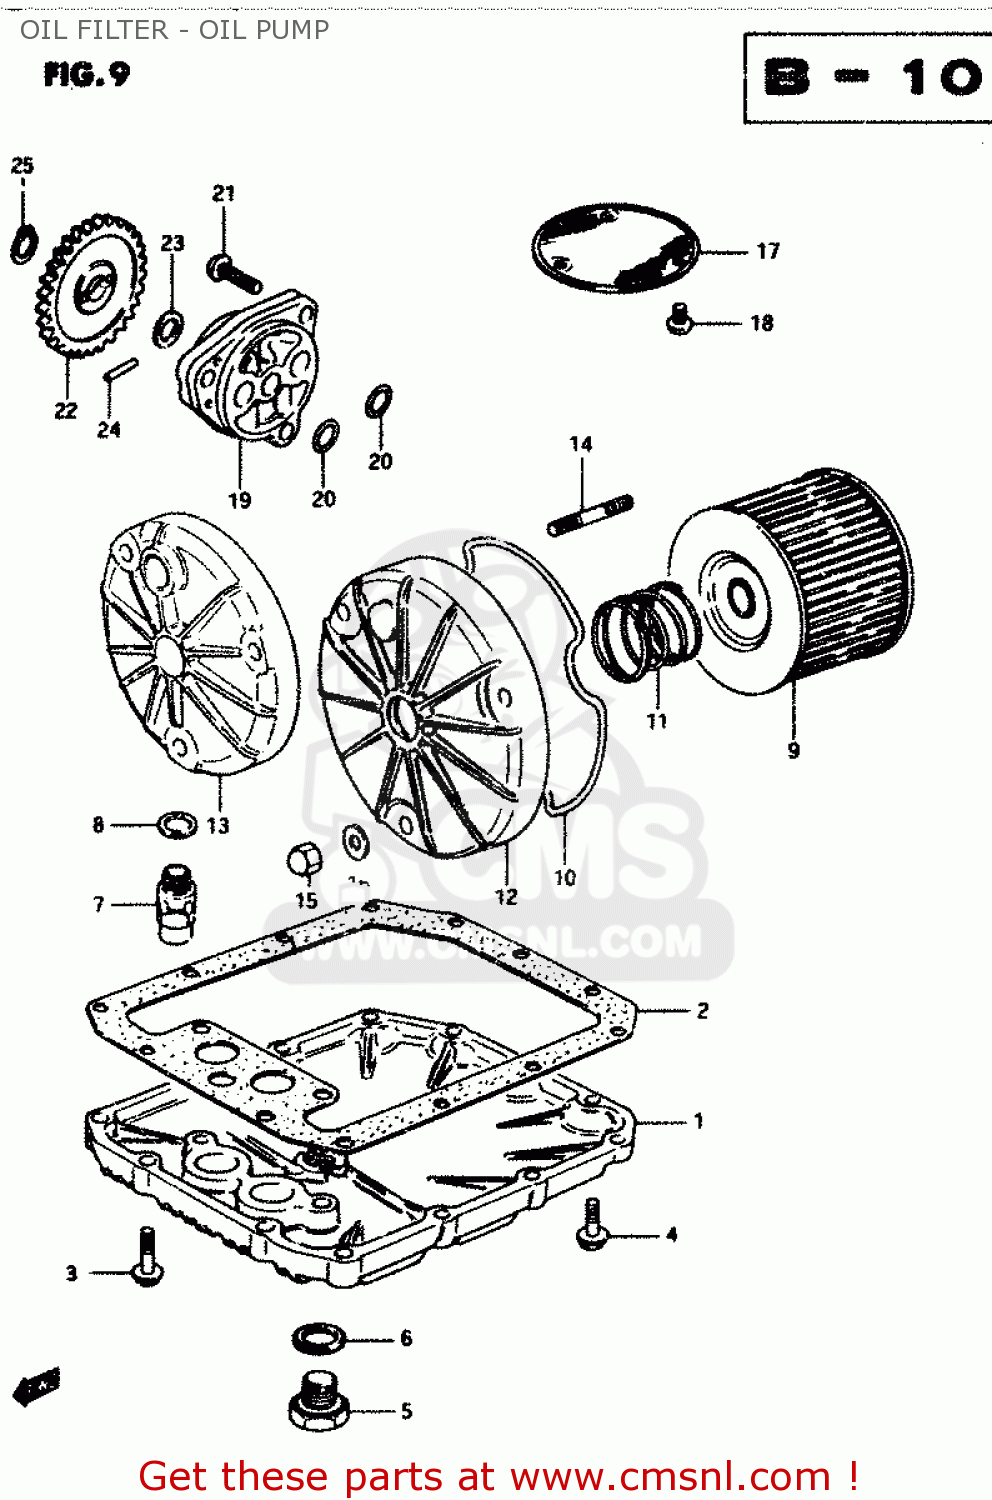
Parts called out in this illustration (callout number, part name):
1	PAN,OIL
2	GASKET,OIL PAN (MCA)
3	BOLT
4	BOLT
5	PLUG
6	GASKET(14X19.2X2) (NAS)
7	REGULATOR ASSEMBLY,ENGINE
8	WASHER
9	FILTER ASSY,ENGINE OIL
10	O RING,OIL FILTER CHAMBER CAP
11	SPRING
12	CAP,ENGINE OIL FILTER
13	CAP,OIL FILTER
14	STUD 6X20
15	NUT
16	WASHER
17	STRAINER,ENGINE OIL
18	SCREW 6X12
19	PUMP ASSY,ENGINE OIL
20	O RING(D:1.9,ID:13)
21	SCREW
22	GEAR,OIL PUMP DRIVEN
23	SHIM
24	PIN(4X15.8)
25	CIRCLIP
